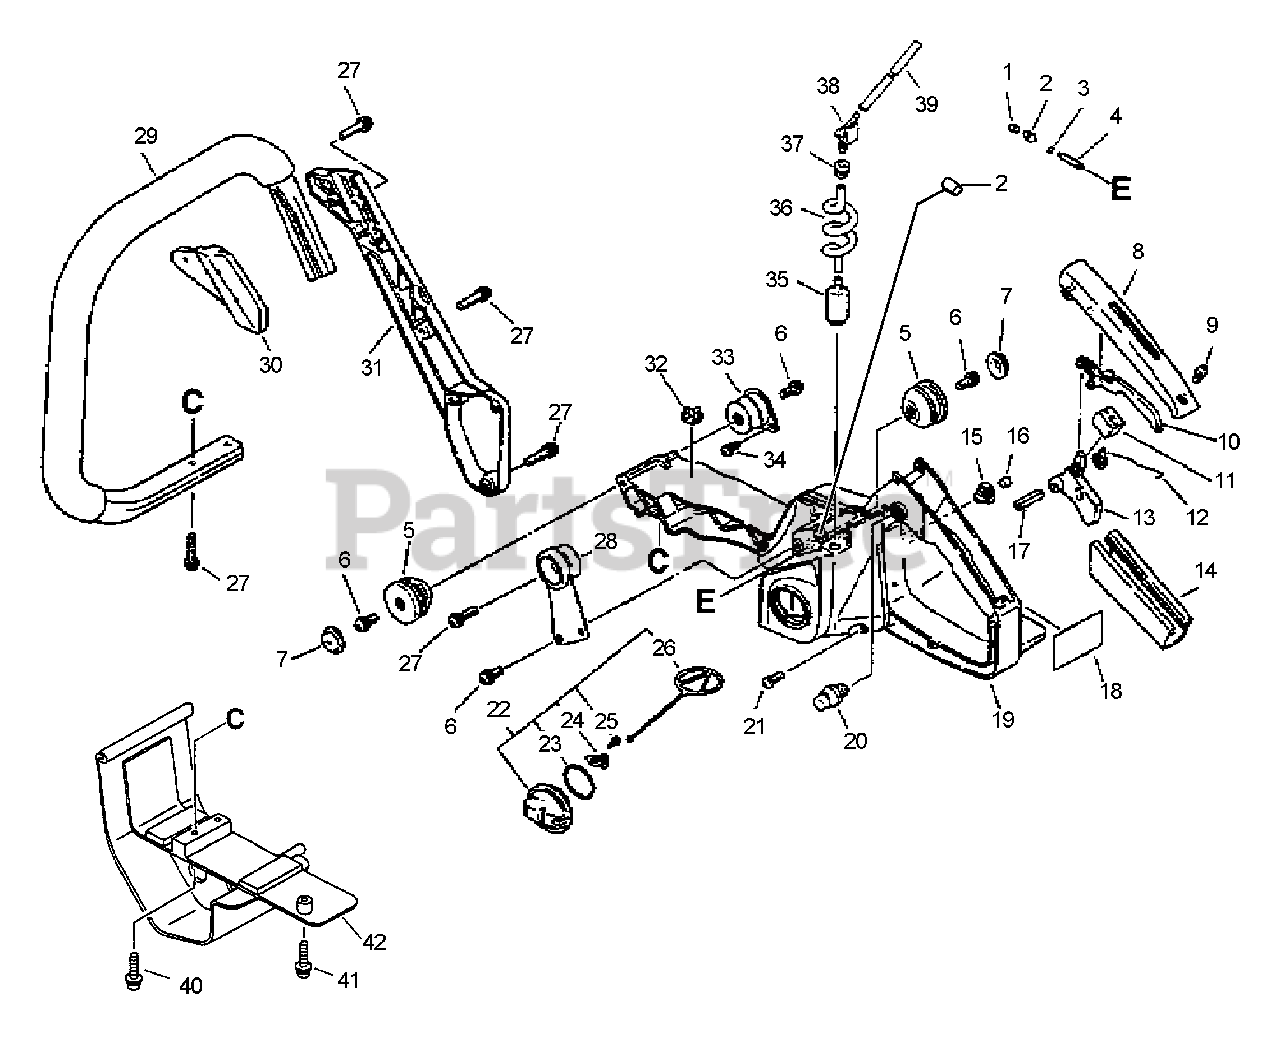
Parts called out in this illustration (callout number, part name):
1	VENT, FUEL TANK
2	COVER, VENT
3	CLIP - 5.5
4	PIPE - 3X5X55 -- BLACK
6	SCREW - 5X14
7	CAP, CUSHION
8	COVER, HANDLE
9	SCREW - 4X14
10	LEVER, TRIGGER LOCKOUT
12	SPRING, TRIGGER
13	TRIGGER, THROTTLE
14	GRIP, HANDLE
15	VENT
15	PLUG
17	PIN - SPRING -- 5X25
18	LABEL - CAUTION
19	HANDLE - REAR
20	LATCH, THROTTLE
21	SCREW - 4X14
22	CAP ASSY
23	O-RING - 29
24	RETAINER
25	SCREW - 3X8
26	CONNECTOR, CAP
27	SCREW - 5X20
29	HANDLE - FRONT
30	BRACKET, HANDLE
31	BRACKET, HANDLE
34	SCREW - 4X10
35	FILTER, FUEL
36	PIPE - BLACK
37	GROMMET
38	CONNECTOR, PIPE
39	PIPE - 3X6X120 -- BLACK
40	SCREW - 5X30
41	SCREW - 5X25
